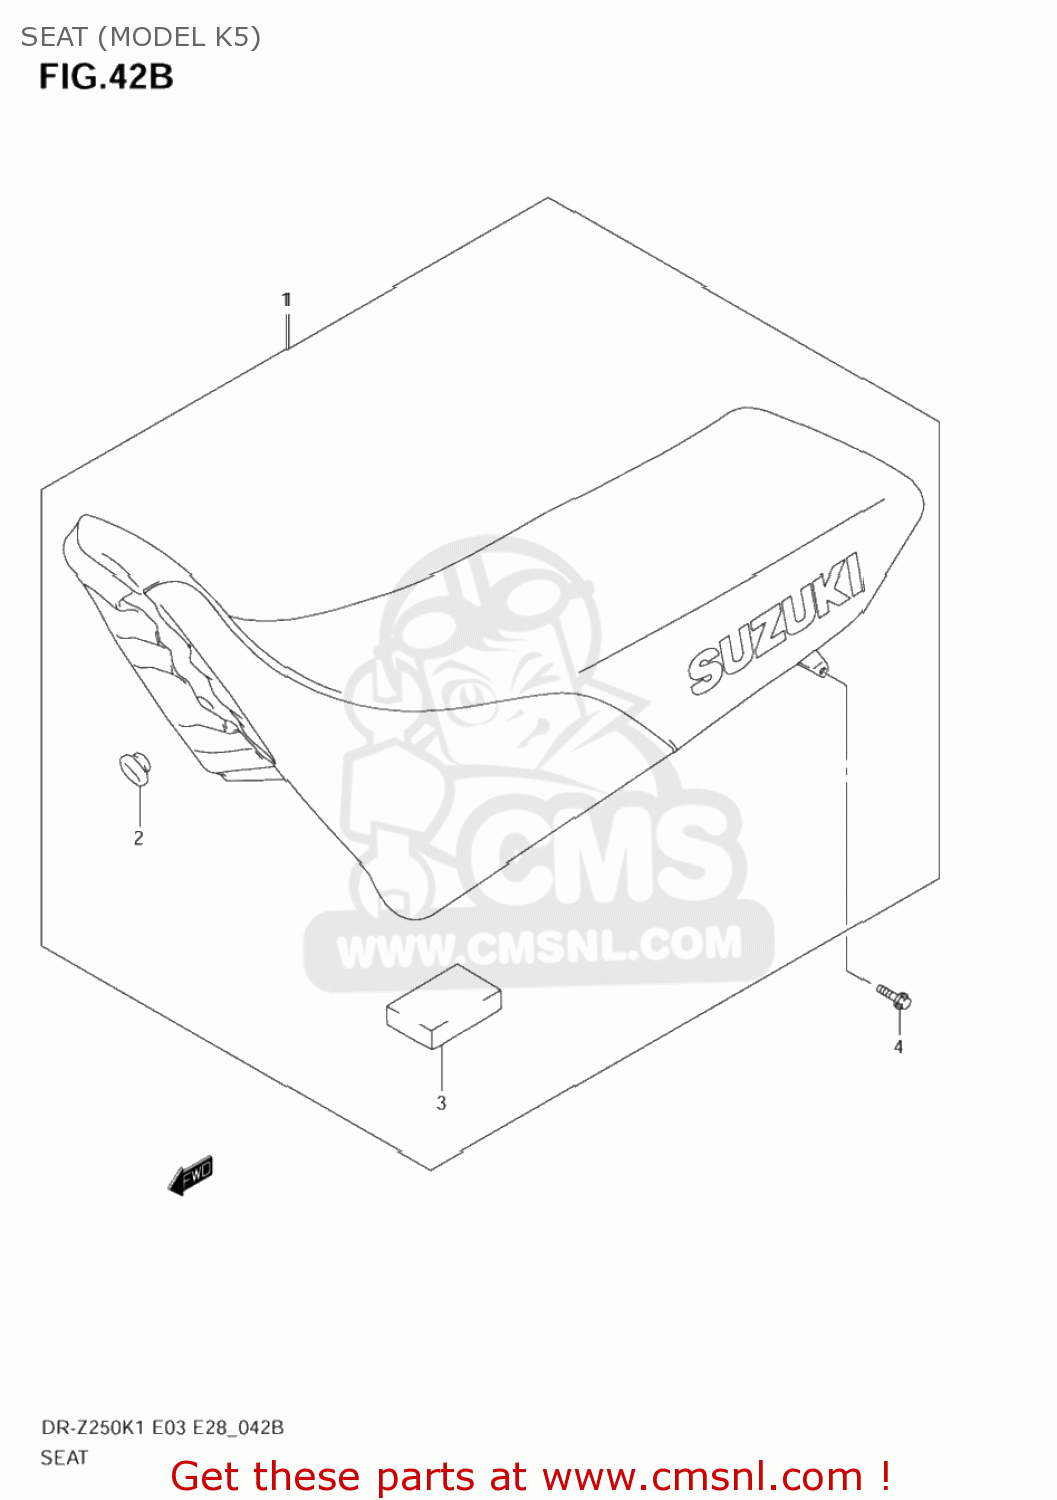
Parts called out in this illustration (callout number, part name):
1	SEAT ASSY
2	CUSHION
3	CUSHION
4	BOLT
